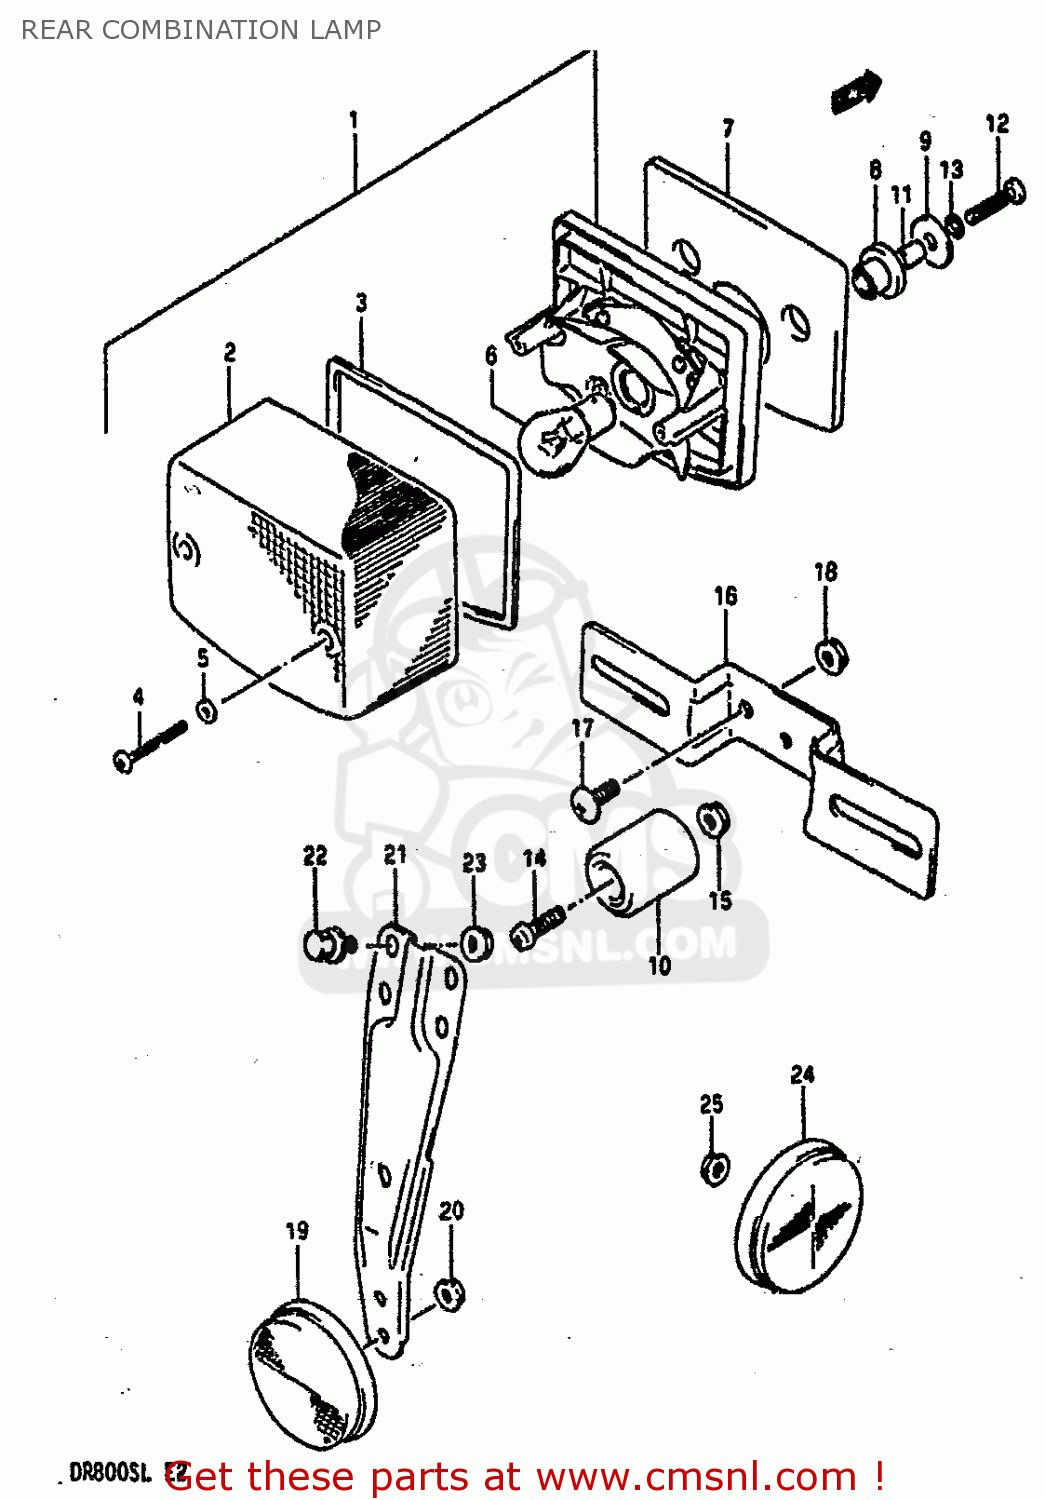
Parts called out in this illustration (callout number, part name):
1	LAMP ASSY,REAR COMBINATION
2	LENS
3	GASKET (NAS)
4	SCREW
5	GASKET (NAS)
6	BULB(12V21/5W)
7	CUSHION
8	CUSHION,REAR COMBINATION LAMP
9	WASHER,REAR COMBINATION LAMP
10	CUSHION
11	SPACER
12	SCREW
13	WASHER,LOCK
14	SCREW
15	NUT
16	BRACKET,LICENSE PLATE
17	SCREW
18	NUT
19	REFLEX REFLECTOR,RR
20	NUT 5MM
21	BRACKET,RR RR
22	BOLT
23	NUT
24	REFLEX REFLECTOR
25	NUT 5MM
